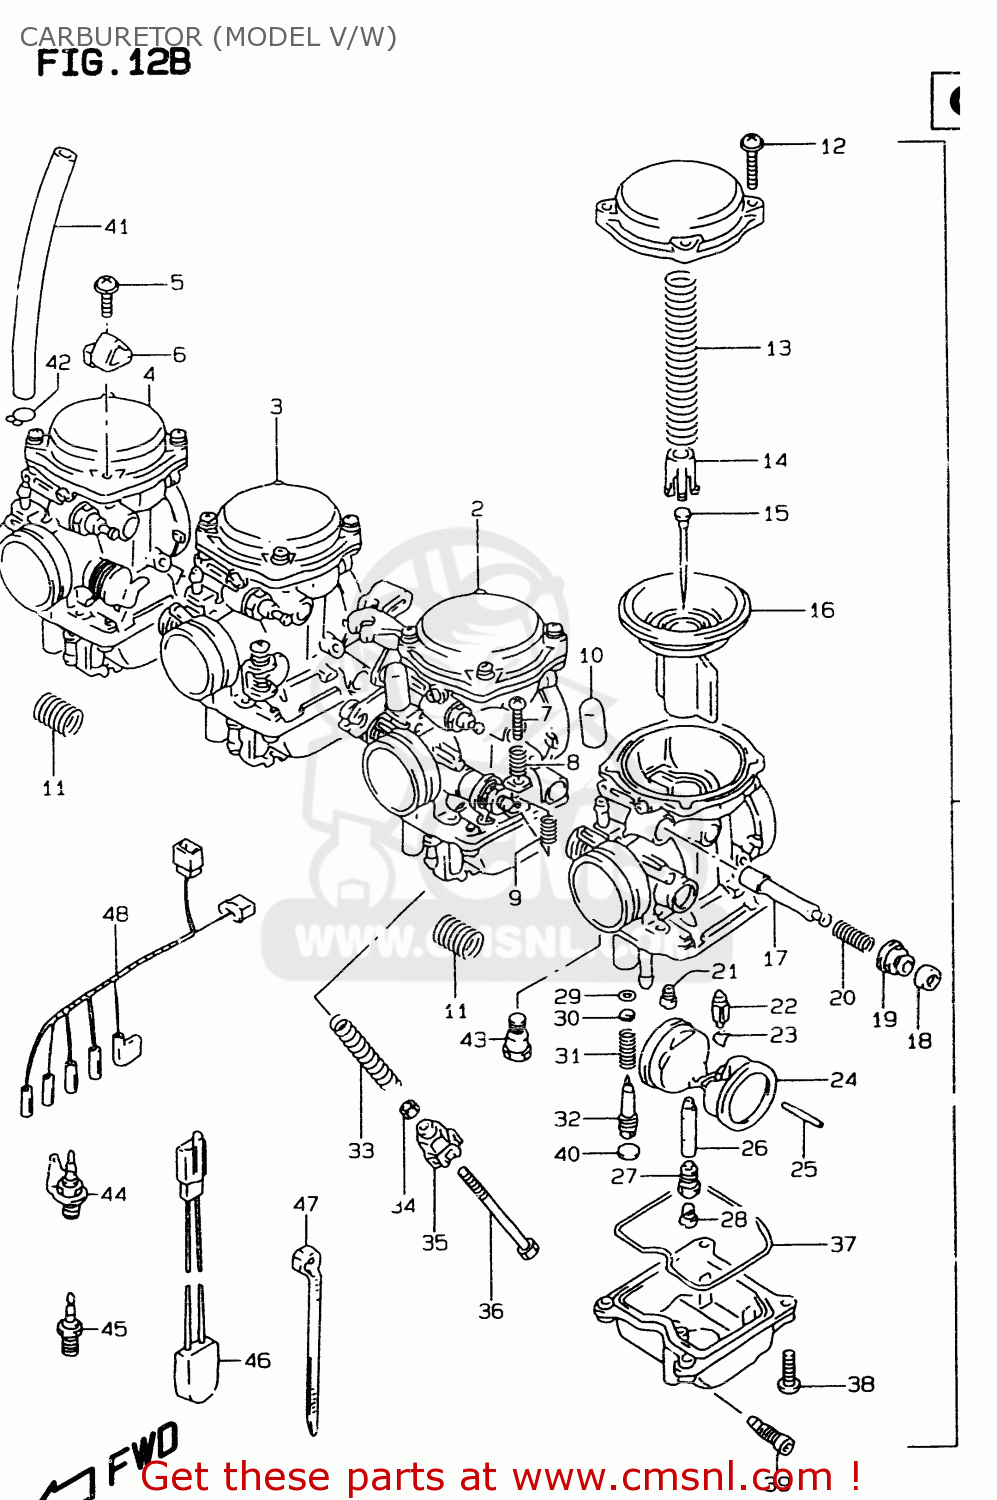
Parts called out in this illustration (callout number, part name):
1	CARBURETOR ASSY, LH
2	CARBURETOR ASSY, ML
3	CARBURETOR ASSY, MR
4	CARBURETOR ASSY, RH
5	SCREW
6	STAY,PLATE
7	SCREW
8	SPRING
9	SPRING
10	CAP
11	SPRING
12	SCREW 4X16
13	SPRING
14	SEAT,SPRING
15	NEEDLE,JET
16	PISTON
17	VALVE,STARTER
18	CAP
19	CAP
20	SPRING
21	JET,SLOW(35)
22	VALVE ASSY,NEEDLE
23	CLIP
24	FLOAT ASSY
25	PIN,FLOAT
26	JET,NEEDLE
27	HOLDER,NEEDLE JET
28	JET,MAIN(100)
29	O RING
30	WASHER
31	SPRING
32	SCREW,ADJUST
33	SPRING
34	WASHER
35	HOLDER,ADJUST
36	BOLT
37	O RING
38	SCREW
39	PLUG,DRAIN
40	CAP
41	HOSE(5X9X600)
42	CLIP
43	ADAPTER,HEATER
44	HEATER ASSY,CARBURETOR(15W)
45	HEATER, CARB.
46	THERMO SWITCH,CARB HEATER
47	CLAMP L:165
48	WIRE,CARB HEATER LEAD
